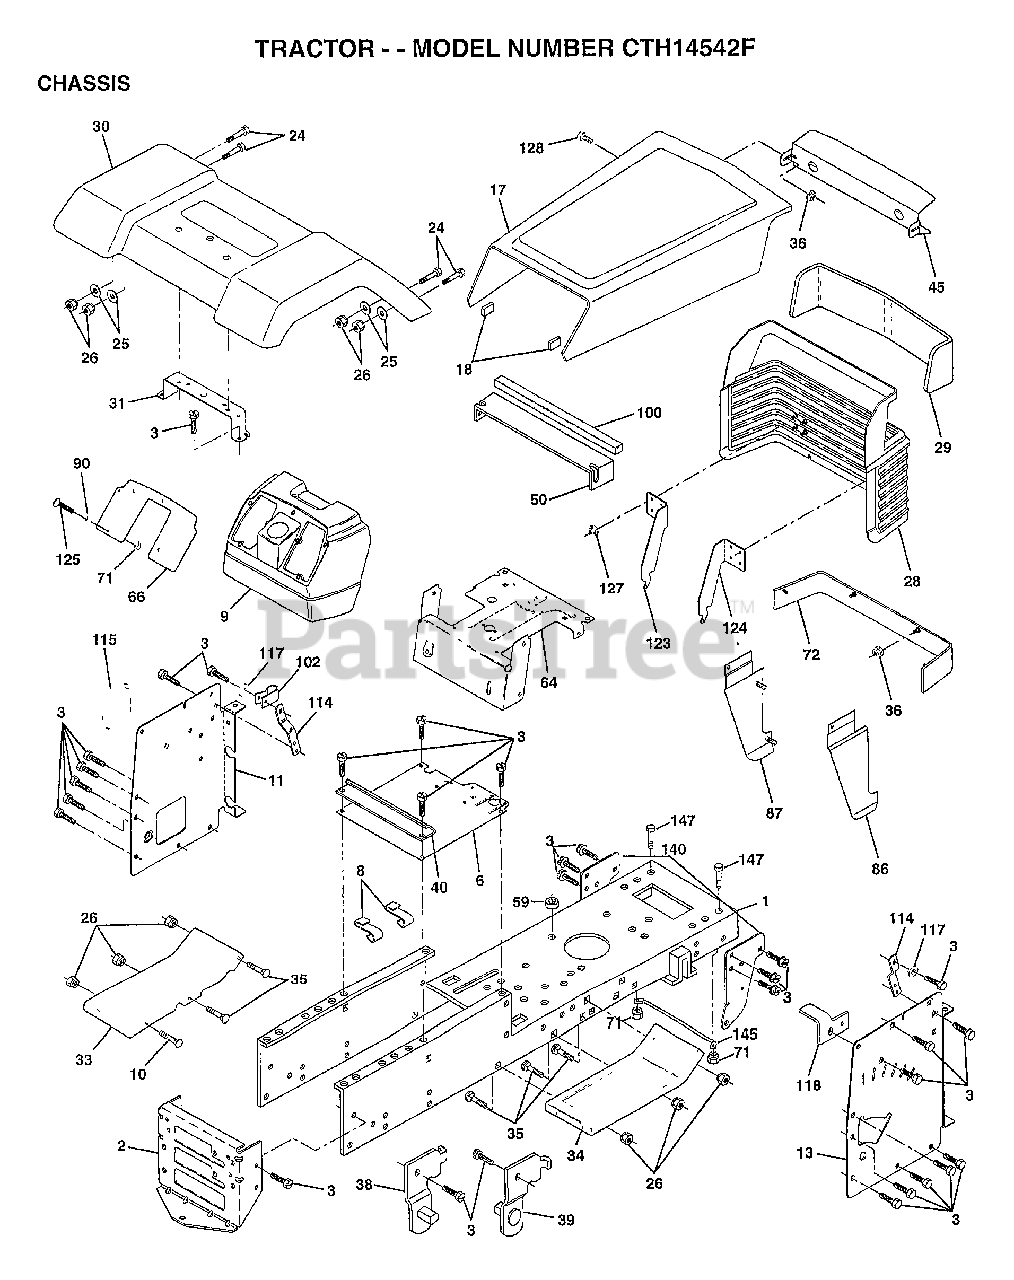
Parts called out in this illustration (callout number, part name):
1	CHASSIS ASM
3	SCREW
6	SADDLE
8	"CLIP,INSULATOR"
9	DASH.PLASTIC.BLK
11	PANEL.DASH.LH.
13	PANEL.DASH.RH.
17	HOOD/GRILLE ASM
24	BOLT
25	WASHER
26	NUT
28	GRILLE ASM WELD
30	FENDER
31	BRACKET SUPT FEND
33	FOOTREST.LH.LT/GT
34	FOOTREST.RH.LT/GT
35	BOLT
36	PAL NUT LT
38	BRACKET ASM LH
39	BRACKET ASM RH
40	SPACER FENDER LT
50	"BAFFLE,HOOD"
64	DASH.LOWER.LT
66	PLATE SLKSCR.OM
72	STRAP FENDER ASM
86	PANEL SIDE RH ASM
87	PANEL SIDE LH ASM
90	WASHER PM
100	FOAM STRIP T
102	CLIP T
114	BRACKET.SUPT.DASH
115	COVER ACCESS
117	WASHER.SERRATED.
118	BRACKET.CLUTCH.MC
123	BRACKET.PICK.LH.
124	BRACKET.PICK.RH.
125	SCREW
127	PAL NUT
128	SCREW SPECIAL
140	BRKT SUSPENSION
145	"ROD POVOT,CHASSIS"
147	BOLT LT
